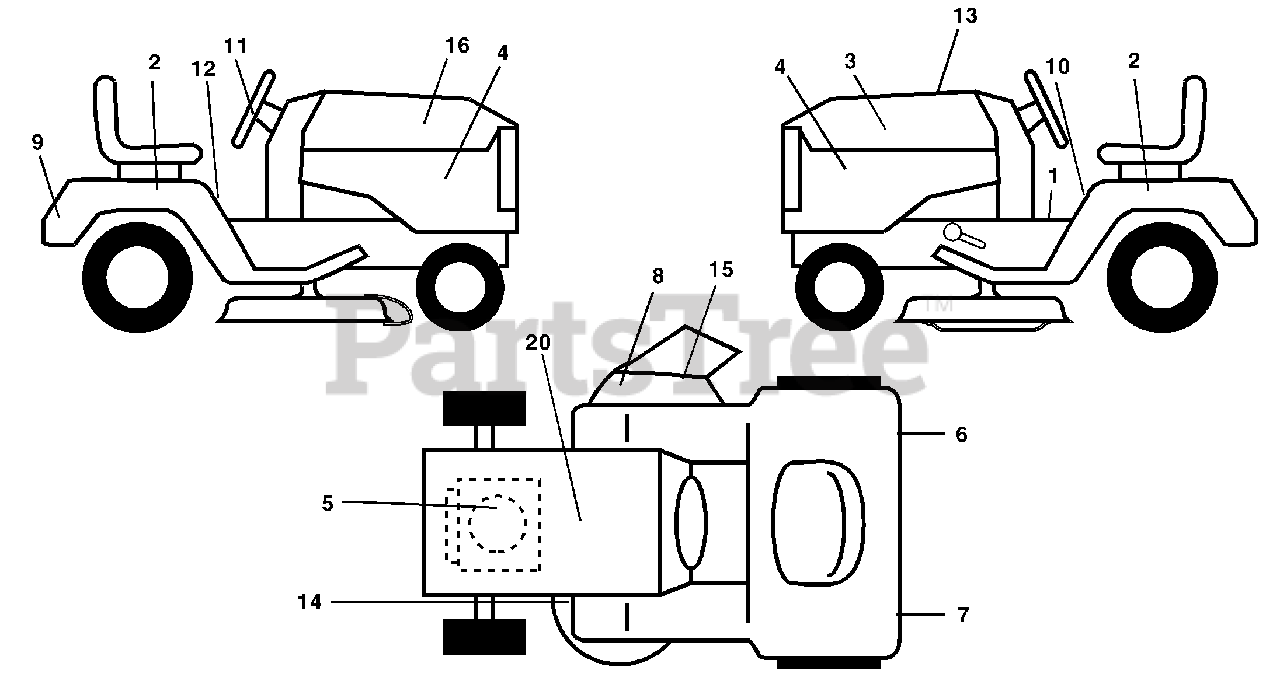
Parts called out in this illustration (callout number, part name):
1	Decal Dash
2	Decal Fender Auto
3	Decal Hood LH
4	Decal Side Panel
5	Decal HP Engine
6	Decal Reflector Rh
7	Decal Reflector Lh
8	Decal Warning Mower
9	Decal Fender Logo
10	Decal Fender Danger E/F
11	Decal Ins Strg Whl
12	Decal Fender Oper Cruise
13	Decal Final Pr-O2F Replace Part
14	Decal V-Belt Schematic
15	Decal Deck B" 42"
16	Decal Hood Rh
20	Decal Bat Dan/Psn
